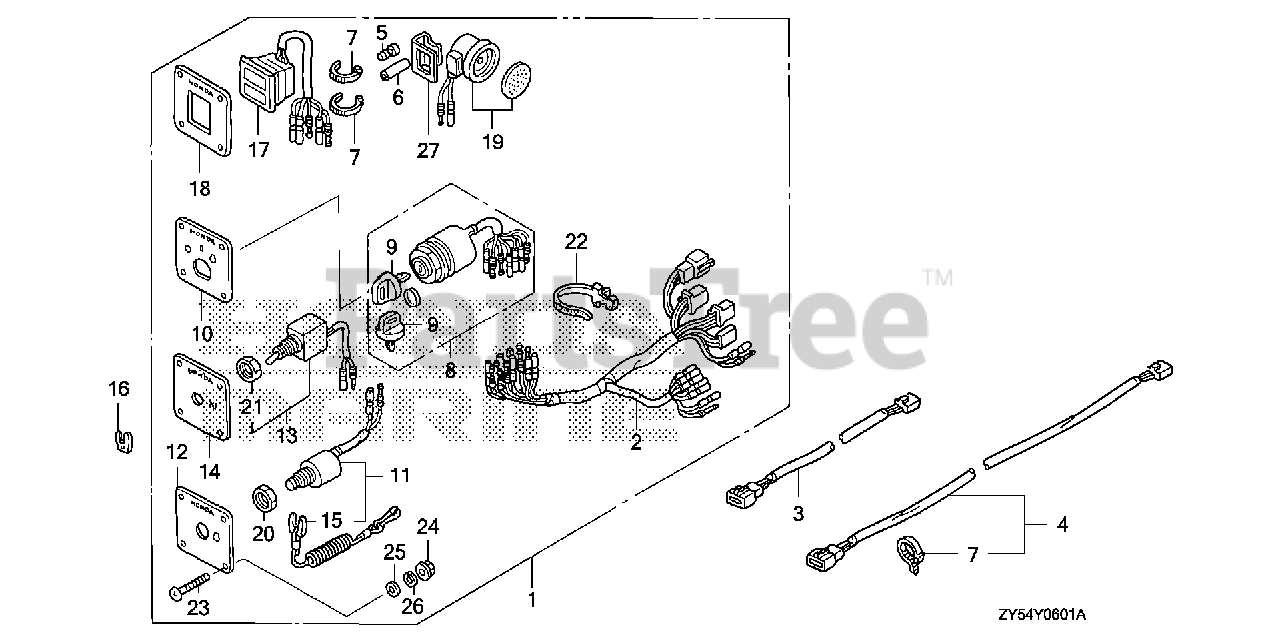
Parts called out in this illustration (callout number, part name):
1	PANEL KIT, CONTROL (2-LED) (A)
2	HARNESS ASSY., SWITCH PANEL
3	CABLE ASSY., EXTENSION (3P 7FT)
4	CABLE ASSY., EXTENSION (3P 30FT)
5	PLUG, CONNECTOR (INNER)
6	PLUG, CONNECTOR (OUTER)
7	TIE, CABLE (2.4X92) (NATURAL)
8	SWITCH ASSY., COMBINATION
9	KEY ASSY., COMBINATION SWITCH (35100-ZV5-003 ONLY)
10	PANEL, SWITCH
11	SWITCH ASSY., EMERGENCY STOP
12	PANEL, EMERGENCY STOP SWITCH
13	SWITCH ASSY., SOLENOID
14	PANEL, SOLENOID
15	WIRE, EMERGENCY
16	CLIP, EMERGENCY LOCK
17	LAMP ASSY., INDICATOR (2-LED)
18	PANEL, INDICATOR
19	BUZZER, WARNING
20	NUT, HEX. (16MM)
21	NUT, HEX. (12MM)
22	BAND, WIRE HARNESS (150MM) (NATURAL)
23	SCREW, PAN (5X40)
24	NUT, FLANGE (5MM)
25	WASHER, PLAIN (5MM)
26	WASHER, SPRING (5MM)
27	BRACKET, BUZZER
